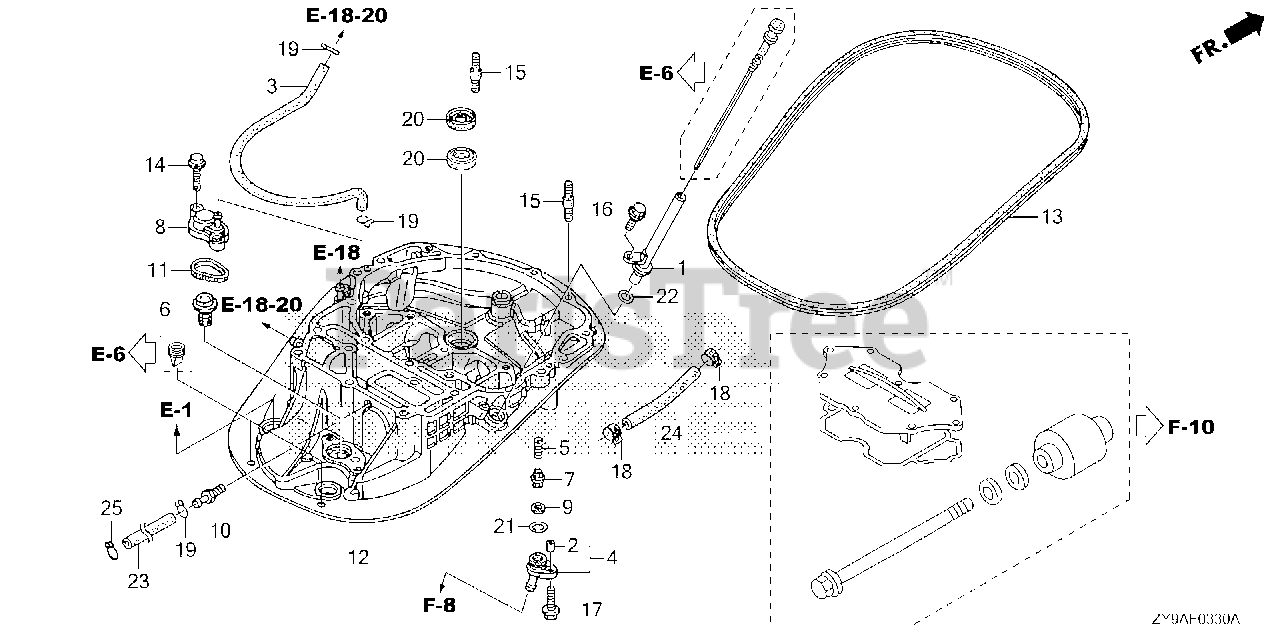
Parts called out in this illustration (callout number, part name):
1	PIPE, OIL LEVEL
2	COLLAR, DISTANCE
3	TUBE B, WATER
4	COVER, FLUSH VALVE
5	SPRING, FLUSH VALVE
6	VALVE ASSY., RELIEF
7	VALVE, FLASH
8	COVER, RELIEF VALVE
9	GASKET, FLASH VALVE
10	JOINT, WATER TUBE
11	O-RING, THERMOSTAT COVER
12	CASE, MOUNT *NH8* (DARK GRAY)
13	SEAL A, COVER (LOWER)
14	BOLT, FLANGE (6X22)
15	BOLT, STUD (8X28)
16	BOLT, FLANGE (6X12)
17	BOLT, FLANGE (6X20)
18	CLAMP, TUBE (D10.5)
19	CLIP, TUBE (B10)
20	SEAL, WATER (22X35X7)
21	O-RING (16MM)
22	O-RING (11.5X3.5)
23	TUBE, WATER CHECK
24	BULK HOSE, VACUUM (7X3000) (7X110)
25	CLIP, TUBE
